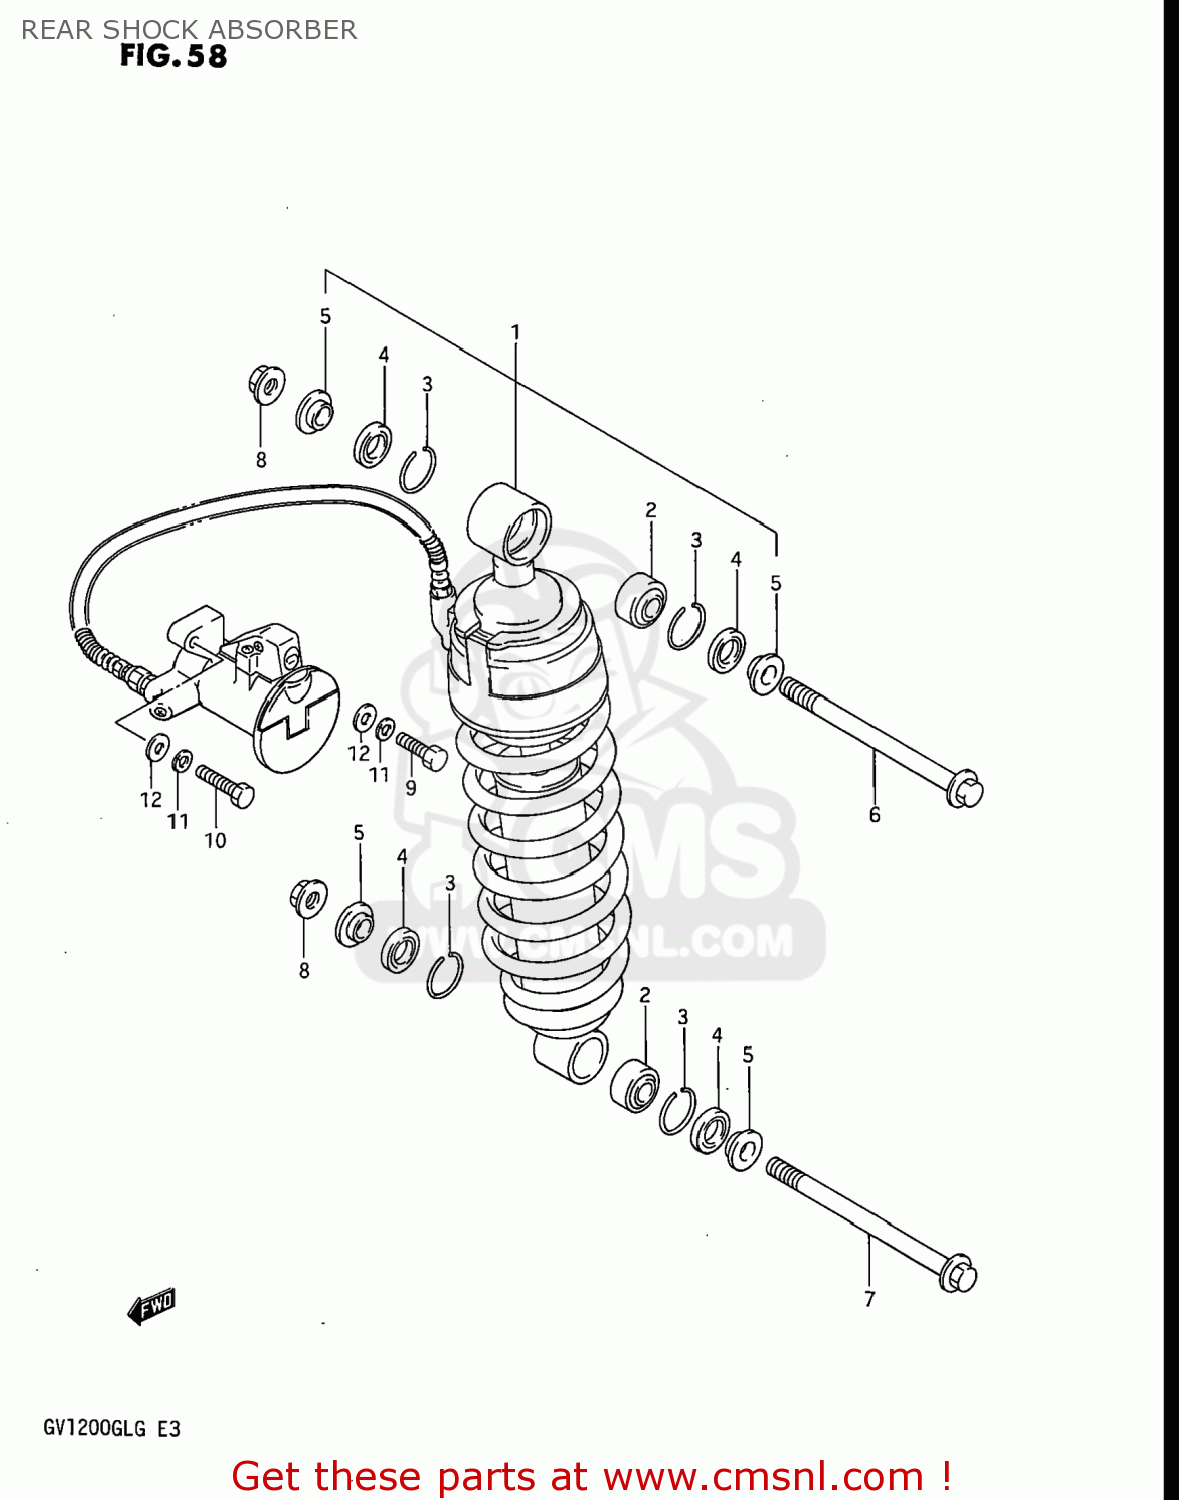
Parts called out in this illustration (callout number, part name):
1	ABSORBER ASSEMBLY,REAR SHOCK
2	BEARING,REAR SHOCK ABSORBER
3	RING
4	SEAL,DUST
5	SPACER
6	BOLT,REAR SHOCK ABSORBER
7	BOLT(10X118)
8	NUT
9	BOLT
10	BOLT
11	WASHER,LOCK
12	WASHER
